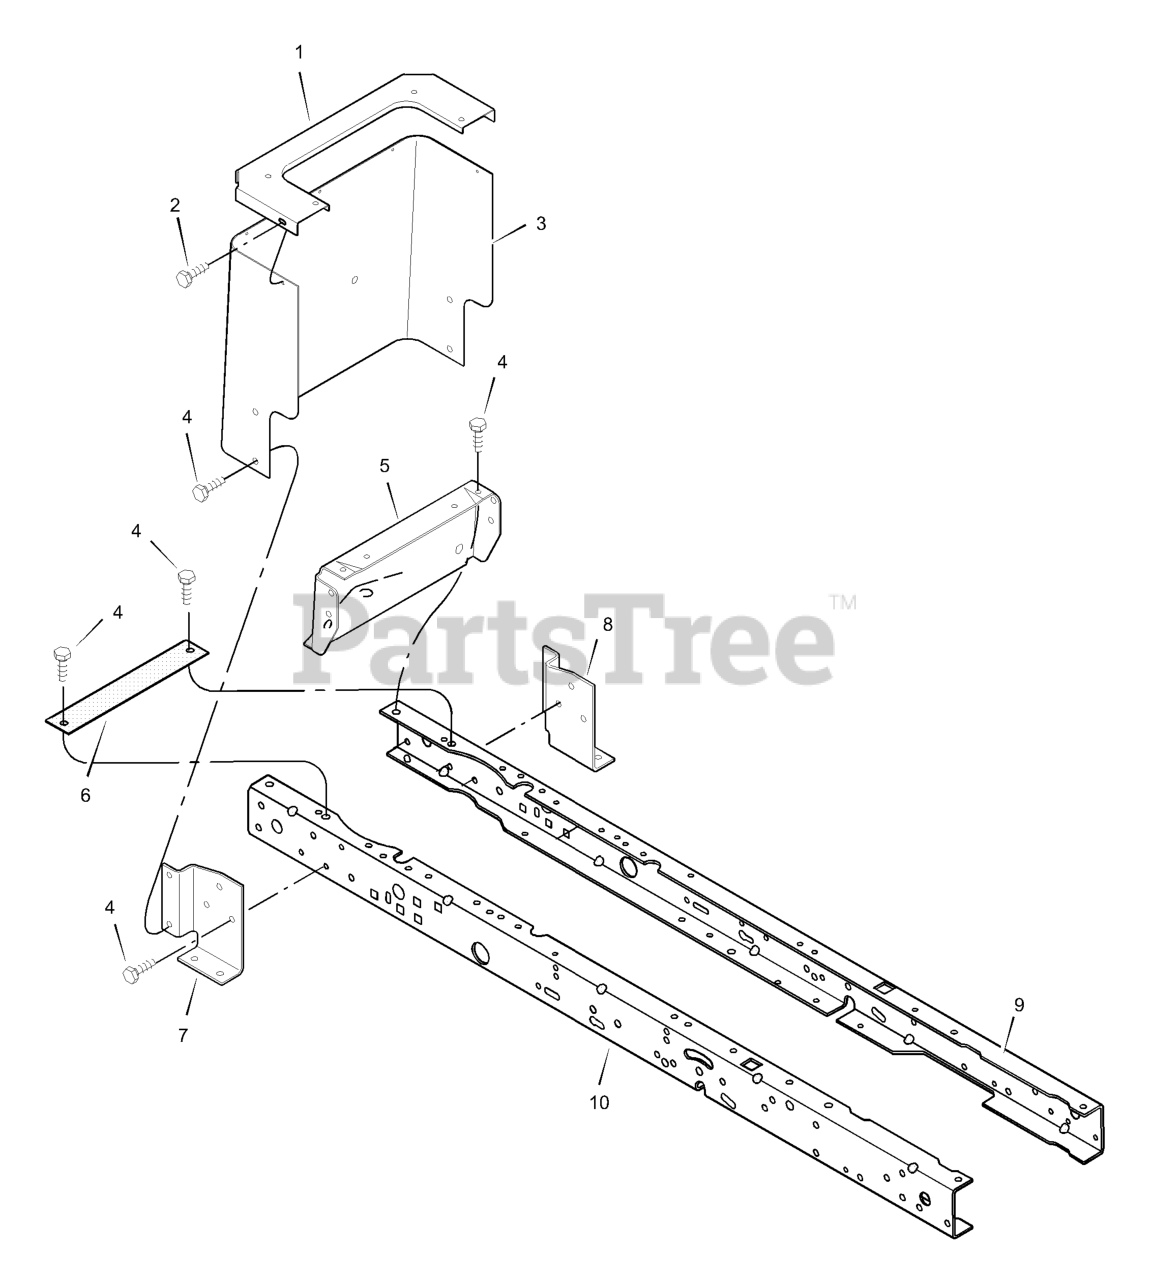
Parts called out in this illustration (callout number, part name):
1	Plate, Top Rear
2	Screw
3	Plate, Rear
5	Plate, Hitch
6	Bracket, Support
7	Bracket, Right Transaxle
8	Bracket, Left Transaxle
9	Frame, Left
10	Frame, Right
